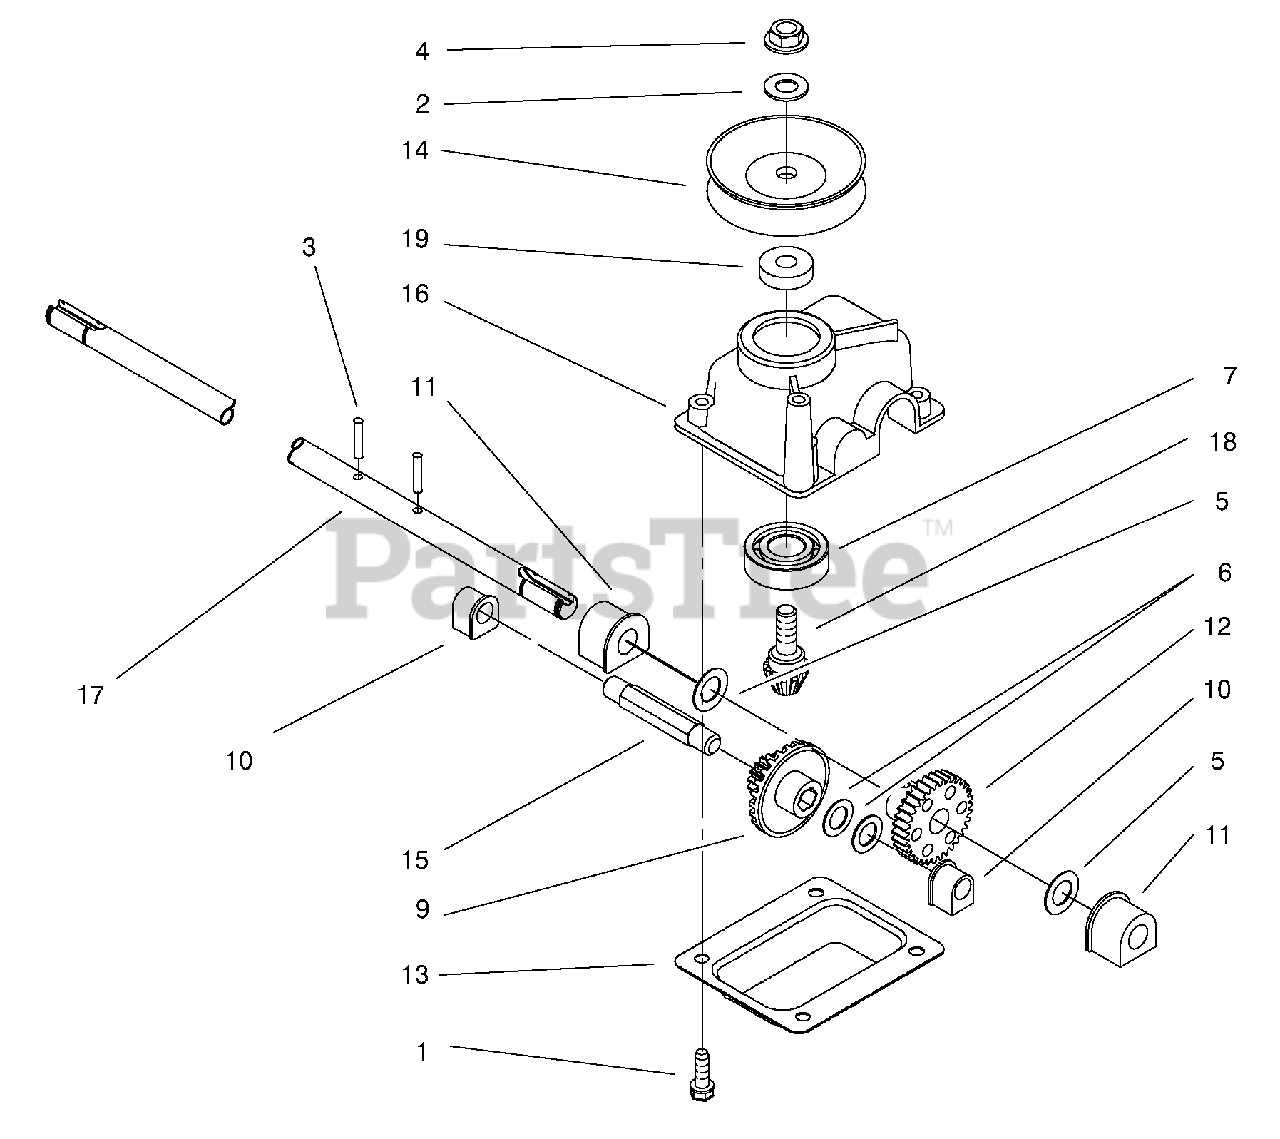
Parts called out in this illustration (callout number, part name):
1	Screw-HH
2	Washer-Flat
3	Pin-Groove
4	Nut-Lock, NI
6	Washer-Thrust
7	Bearing-Ball
9	Gear-Bevel
11	Bushing-Output
13	Cover-Gear Case
14	Half-Pulley
15	Shaft-Intermediate
16	Gearcase
17	Shaft-Output
18	Pinion-Bevel
19	Spacer-Pulley
